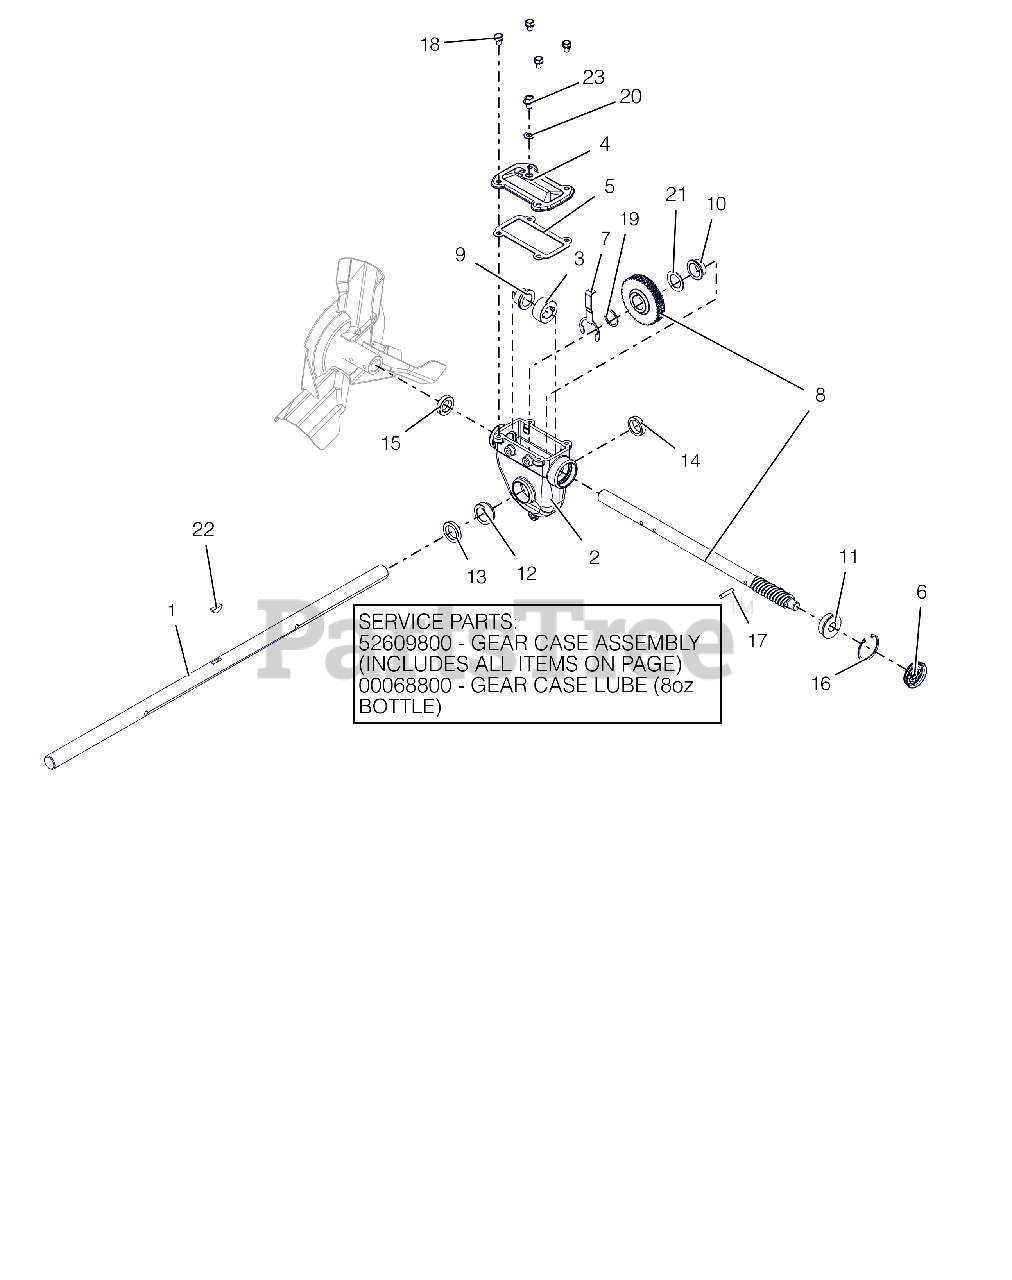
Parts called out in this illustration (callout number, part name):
1	SHAFT, RAKE-32"
2	GEARCASE, LARGE MACHINED
2	GEAR CASE, 32" IRON PRO TOP-LD
2	ARIENS L3 LUBE, 8 OZ BOTTLE
3	THRUST COLLAR, .875"ID SLIPFIT
4	COVER, TOP - LARGE IRON
5	GASKET, TOP - LARGE GEARCASE
6	COVER, GEAR CASE 1.75"
7	BUSHING RETAINER, LARGE
8	ASSY, WORM SHAFT & GEAR
9	BSHG-FLG .879X1.128X.75X1.45
10	BSHG-FLG 1.006X1.128X.555X1.45
11	BSHG-FLG .628X1.503X.58X1.725
12	BSHG-FLG LARGE, RIGHT
13	SEAL-OIL .999X1.500X.250 TBC29
14	SEAL-OIL .999X1.375X.312 TBC29
15	SEAL-OIL .873X1.375X.312 TBC29
16	RG-RTNG-INT 1.750X.062
17	PIN-STR .250X1.12 6150
18	BOLT, SEMS .31-18X.50 GR5 YWZC
19	WSHR-FL-STL 1.010X1.250X.068YZ
20	WSHR-BND-SEAL .38X.75X.11 GALV
21	WSHR-FL-STL 1.010X1.505X.062YZ
22	KEY-WDRF .25X.875 HRD #A
23	@SCR-ROLOK .38-16X.50 HWH YWZC
